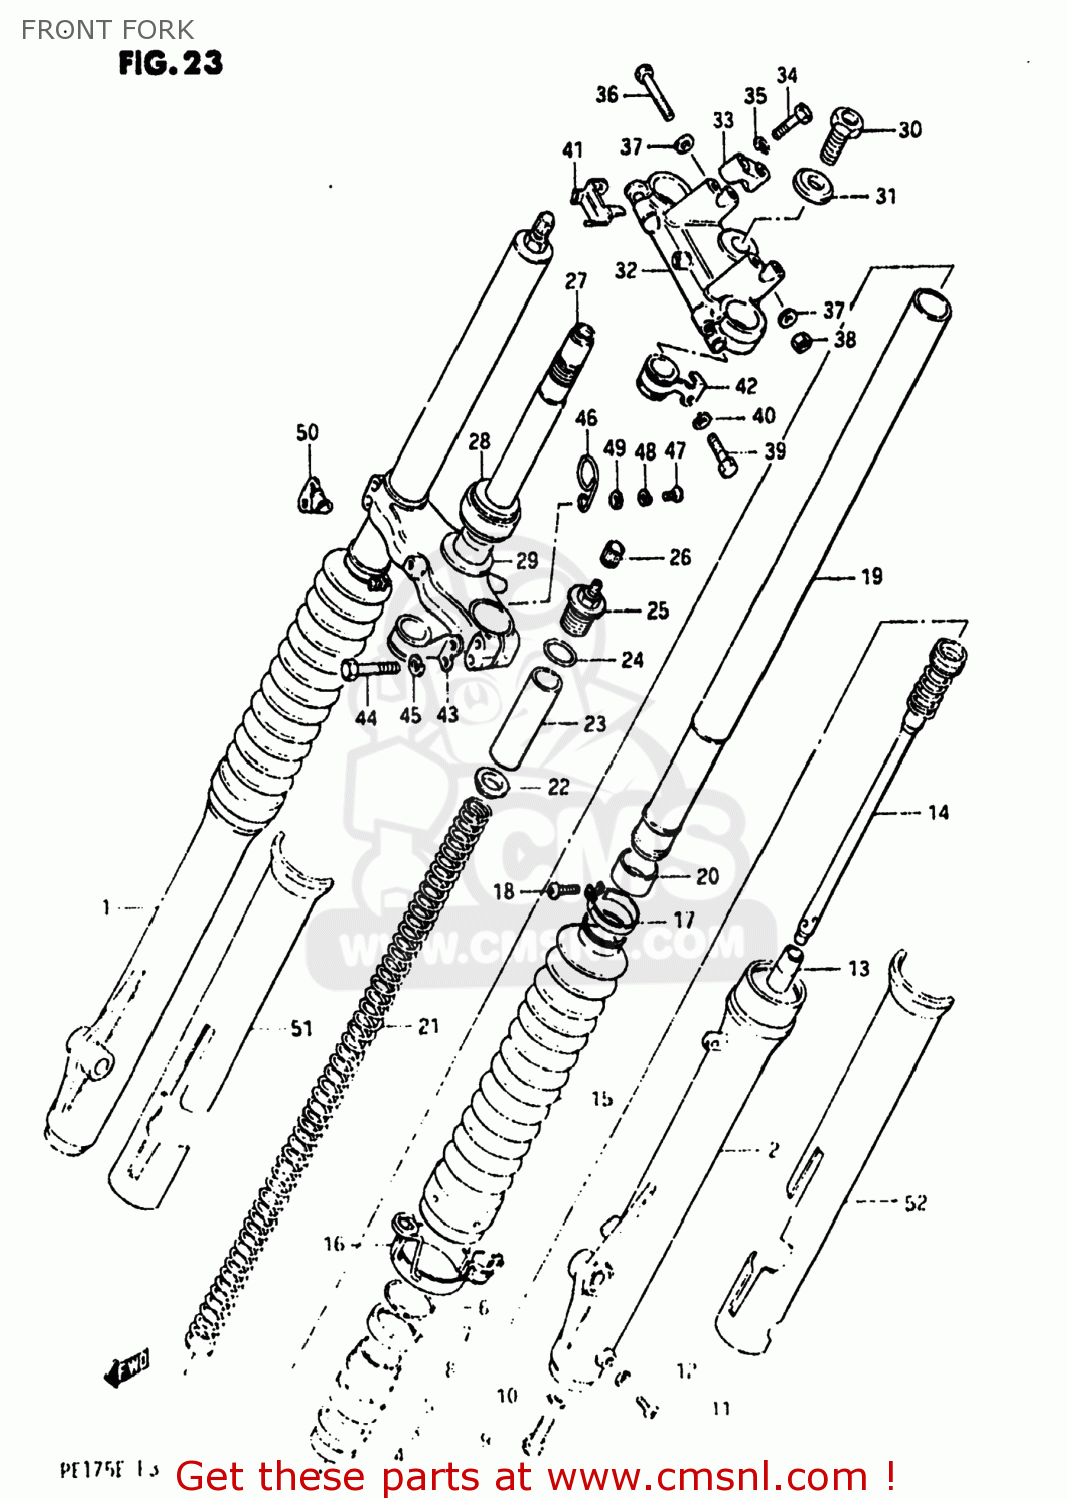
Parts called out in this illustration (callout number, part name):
1	TUBE,OUTER,RIGHT
2	TUBE,OUTER,LEFT
3	WASHER(40X50X2.3)
4	METAL,SLIDE
5	SEAL,OIL
6	RING,STOPPER
7	CASE,DUST SEAL
8	SEAL,DUST
9	BOLT,CYLINDER
10	GASKET,CYLINDER (NAS)
11	SCREW
12	GASKET,DRAIN,PLUG (NAS)
13	PIECE,OIL LOCK
14	CYLINDER,FRONT FORK
15	BOOT,FRONT FORK COVER
16	BAND,FORK COVER BOOT
17	BAND,BOOT
18	SCREW 4X10
19	TUBE,FORK,INNER
20	PISTON
21	SPRING,FRONT FORK
22	GUIDE
23	SPACER,FRONT FORK SPRING
24	O RING
25	BOLT,STEERING STEM HEAD
26	CAP
27	STEM,STEERING
28	BEARING
29	WASHER,THRUST
30	BOLT
31	WASHER
32	HEAD,STEERING STEM
33	HOLDER,HANDLEBAR
34	BOLT
35	LOCK WASHER
36	BOLT 8X50
37	WASHER
38	NUT
39	BOLT
40	LOCK WASHER
41	BRACKET,TOOL FITTING,UPPER
42	GUIDE,CABLE
43	CLIP,CABLE
44	BOLT 8X45
45	LOCK WASHER
46	CLIP
47	SCREW
48	LOCK WASHER
49	WASHER
50	BRACKET,TOOL FITTING,LOWER
51	PROTECTOR,FRONT FORK,RIGHT
52	PROTECTOR
